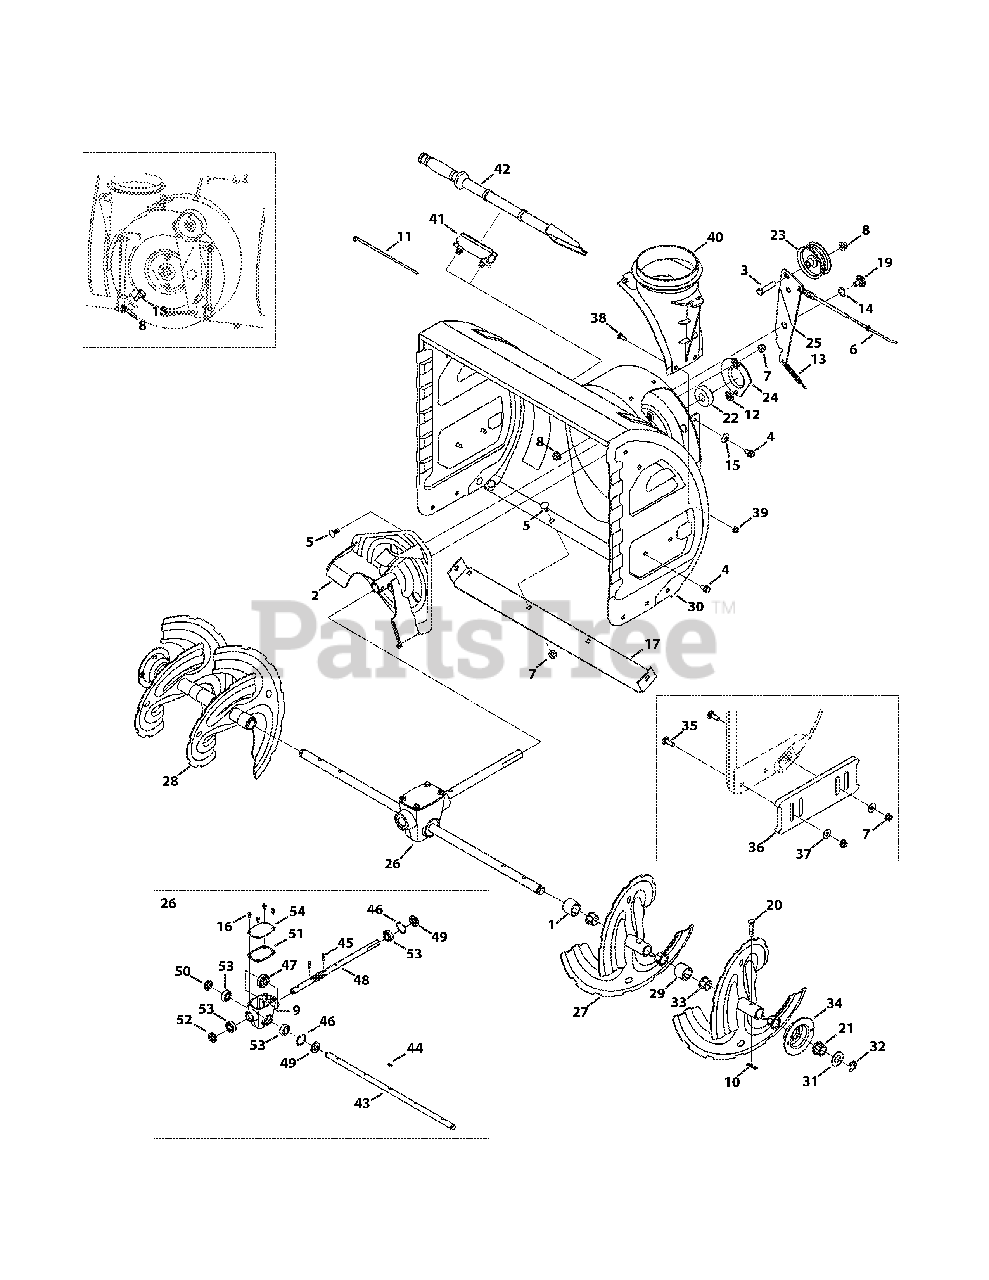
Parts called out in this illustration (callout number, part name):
1	Spacer, 1.25 x .75 x 1.312
2	Impeller Assembly
3	Hex Bolt, 3/8-16 x 1.75
4	Screw, 5/16-18 x .750
5	Carriage Bolt, 5/16-18 x .750
6	Auger Clutch Cable
7	Flange Lock Nut, 5/16-18
8	Flange Lock Nut, 3/8-16
9	Auger Housing
10	Bow Tie Cotter Pin
11	Cable Tie
12	Push-On Nut, .25 Dia.
13	Extension Spring, .38 OD x 4.59
14	Wave Washer, .625 x .885 x .0175
15	Bell Washer, .340 x .872 x .060
16	Screw, 1/4-20 x 0.75
17	Shave Plate, 24"
18	Shoulder Screw, 3/8-16 x .496 x .336
19	Shoulder Screw, 3/8-16 x .625 x .17
21	Hex Flange Bearing
22	Flange Ball Bearing, .75 x 1.85
23	Flat Idler Pulley
24	Bearing Housing
26	Gearbox Assembly, Auger, 24"
27	Spiral Assembly - LH
28	Spiral Assembly - RH
29	Spacer, 1.25 x .75 x 1.00
30	Auger Housing, 24"
31	Flat Washer, .76 x 1.49 x .06
32	E-Ring, .750
33	Flange Bushing, .800 x .910
34	Hex Bearing Housing
35	Spacer, Carriage, 5/16-18 x 1.00
36	Deluxe Slide Shoe
37	Washer, Flat, .349 x .879 x .063
38	Carriage Screw, 1/4-20 x 0.75
39	Flange Lock Nut, 1/4-20
40	Chute Adapter
41	Clean-out Tool Mtg. Bracket
42	Clean-Out Tool
43	Axle, Auger, 24"
44	Hi-Pro Key
45	Pin, Roll, .25 x 1.0
46	Retainer Ring
47	Worm Gear, 20T
48	Worm Shaft
49	Seal, .75 x 40mm x .25
50	Seal, .75 x 1.375 x .25
51	Gearbox Gasket
52	Plug, 1.375 OD x .25
53	Ball Bearing, .75 x 40 x 12
54	Gearbox Cover
